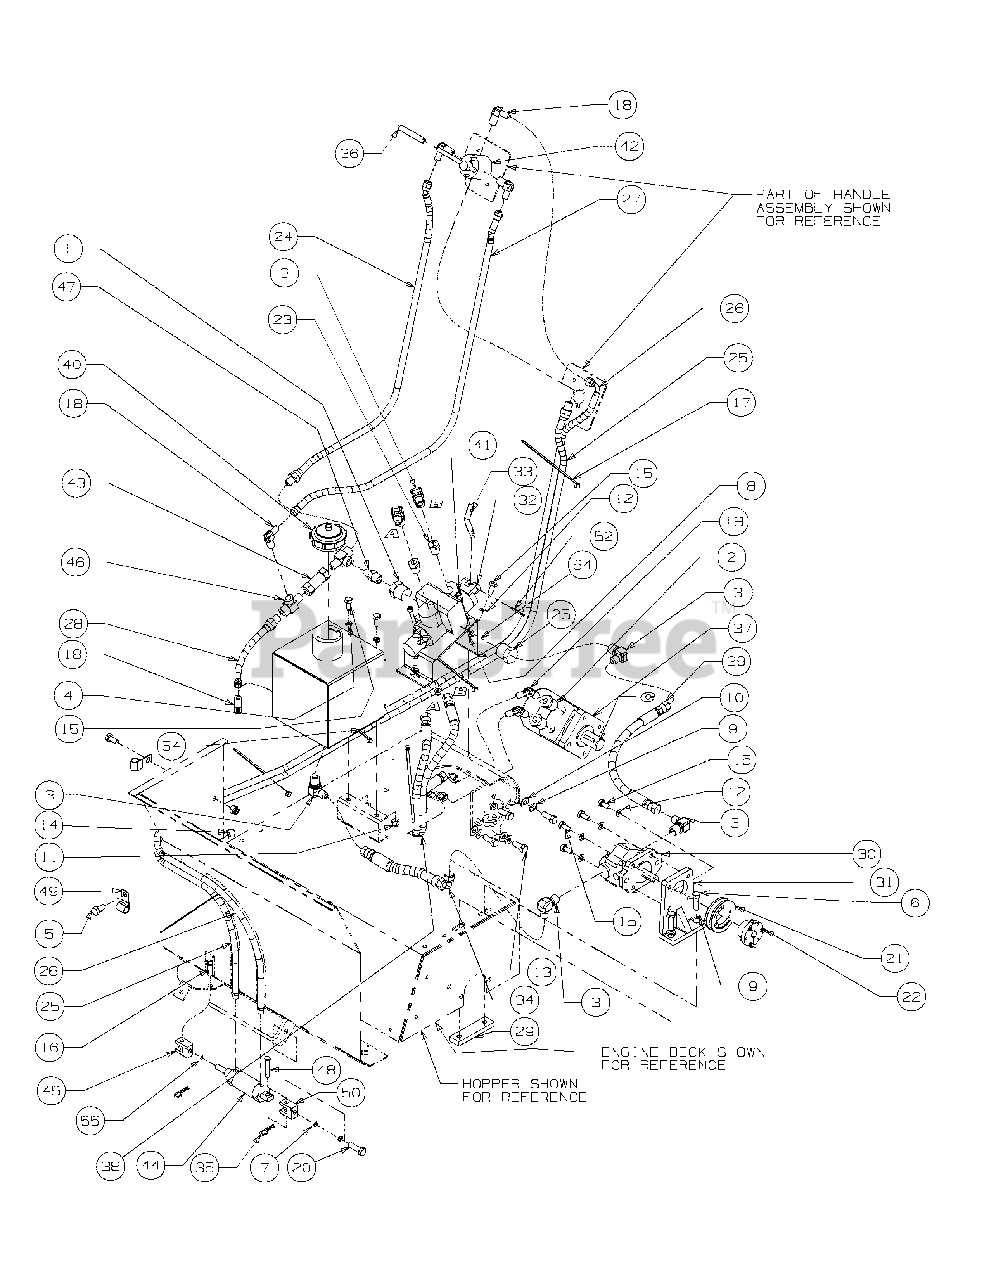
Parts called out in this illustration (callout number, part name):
1	Reducer Fitting, 3/4 x 3/8
2	Reducer Fitting, 1/2 x 1/4
3	Elbow Fitting
4	Flat Washer, 5/16
5	Hex Cap Screw, 3/8-16 x 3/4
6	Hex Cap Screw, 3/8-16 x 1-1/4
7	Jam Hex Nut, 3/8-24
8	Lock Nut, Nylon Insert, 1/4-20
9	Lock Washer, 3/8
10	Flat Washer, 3/8
11	Nylock Nut, 5/16-18
12	Lock Washer, 5/16
13	Hex Cap Screw, 3/8-16 x 1
14	Lock Nut, Nylon Insert 3/8-16
15	Hex Cap Screw, 5/16-18 x 3/4
16	Clevis Pin, 5/16 x 1
17	Cable Tie, 3/16 x .05 x 7.4
18	Hydraulic Fitting
19	Reel Return Line Sleeve, 1.25
20	Hex Cap Screw, 3/8-24 x 1-1/4
21	Sheave Pulley
22	Sheave Bushing Pulley Hub
23	Reducer Fitting, 3/8 x 1/4
24	Valve To Valve Hose
25	Open Cylinder Hose
26	Closed Cylinder Hose
27	Hose to Return Valve
28	Return Hose
29	Nut Bar, Pump
31	Pump Mount
33	Handle Valve
34	Hydraulic Tank Blower Hose
35	3/8"-1/2" Hair Pin
36	Grip
37	Hydraulic Motor
38	Hydraulic Motor Hose
39	Pressure Hose
40	Hydraulic Oil Tank Cap
41	Capscrew, 1/4-20 x 1-1/2
42	Brand Select Valve
43	Pressure Relief Valve
44	Cylinder, 1-1/8 Bore
45	Clevis Cylinder
46	Aeroquip, Fitting
47	Aeroquip, Fitting
48	Clevis Pin, 5/16 x 1-5/8
49	Support Clamp, 3/4
50	Mounting Cylinder, Yoke
51	Teflon Tape, 1/2" Wide
52	Spring Pin, 1/8 x 1-3/8
53	Valve Mounting Bracket
54	Hydraulic Tank Assembly
55	Jam Lock Nut, 5/16-18
